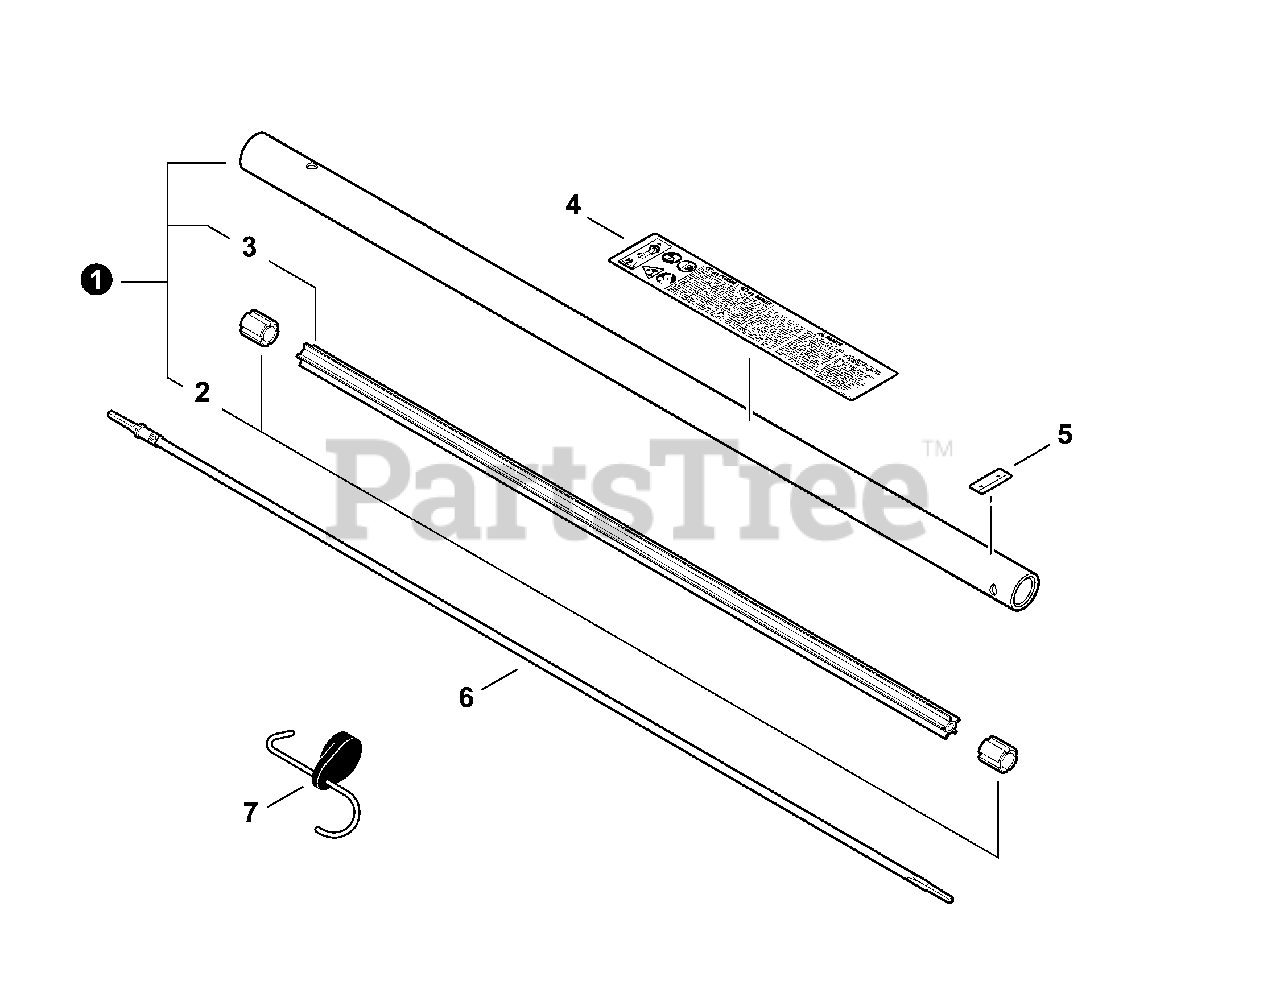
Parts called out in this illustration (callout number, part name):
1	MAIN PIPE ASY
3	LINER - FLEXIBLE
4	LABEL - CAUTION
5	LABEL - ALIGNMENT
6	DRIVESHAFT - FLEXIBLE
7	PAS ATTACHMENT HANGER
